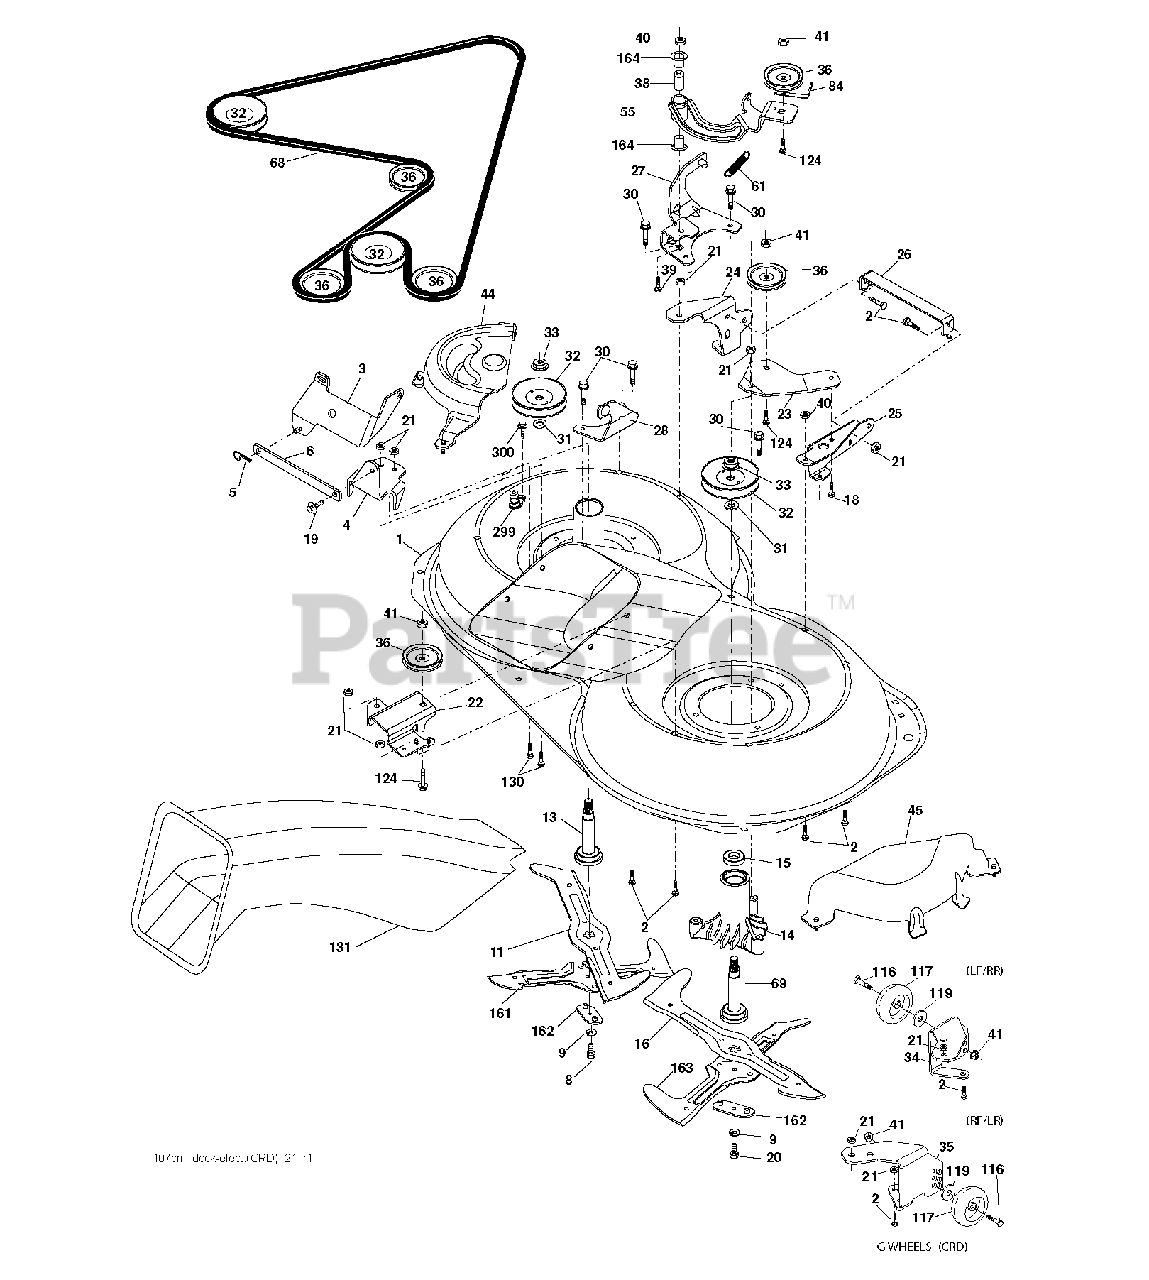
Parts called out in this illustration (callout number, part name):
2	BOLT
3	BRACKET.ASM.BAR.SWAY.CHASS
5	RETAINER-SPRNG RB
6	BAR SWAY
9	LOCKWASHER
11	BLADE.3N1.LH.CRD
13	SHAFT ASM VENT
14	HSG MANDREL
16	BLADE.3N1.RH.CRD
18	BOLT
19	BOLT SHD 5/16-18
21	LOCKNUT
22	BRACKET
23	BRACKET
27	BRACKET
30	SCREW, WASHER HEAD
31	WASHER.SPACER.MANDREL
33	NUT.FLANGE.LOCK.TOP
36	PULLEY.IDLER.4.25
40	LOCKNUT
41	NUT LOCK FLG 3/8-16 UNC
55	ARM IDLER
68	HEX-BELT 107 MOWER
69	SHAFT.ASM.W/LWR.BRG.RH.THREAD
84	KEEPER, BELT IDLER
116	BOLT.SHOULDER.3/8-16X3-5/8
117	WHEEL. GUAGE RALLY
124	BOLT.3/8-16X1.50
131	CHUTE BAGGER
164	BRNG T
299	PORT.WASHOUT
